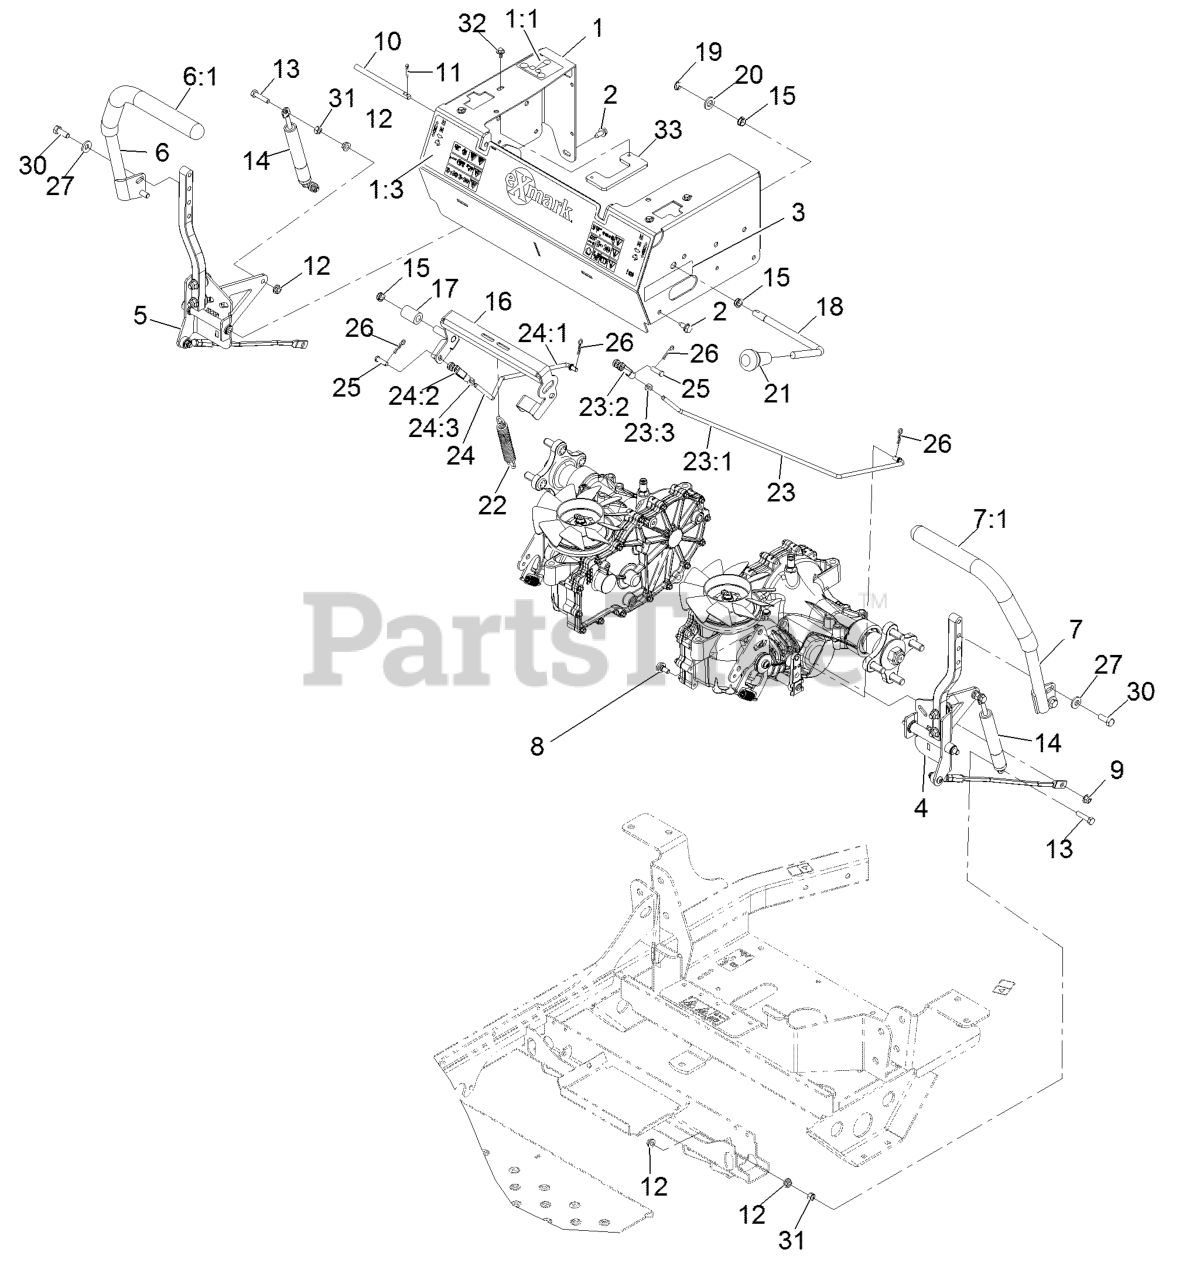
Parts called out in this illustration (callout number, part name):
1	ASM-MOT CTRL FRM W/DCL
1:1	DECAL-ROUTING, BELT
1:3	DECAL-CONSOLE
2	Screw-HWH 5/16-18 X 3/4 Tf
3	DECAL-S-SERIES
4	Motion Control ASM-LH
5	Motion Control ASM-RH
6	RH HANDLE ASM
7	LH HANDLE ASM
8	BOLT-SHOULDER,HFH
9	NUT-HF, NI
10	PIN-CONTROL PIVOT
11	PIN-COTTER
13	SCREW-HH
14	DAMPER-MOTION CONTROL
15	BUSHING,SNAP
16	ASM-BRAKE CENTER ARM
18	HANDLE,BRAKE
19	RING-RETAINING, EXTERNAL
20	WASHER-FLAT
22	SPRING-DECK, ENGAGEMENT
23	BRAKE LINKAGE ASM-LH
23:1	LINKAGE,BRAKE LH
23:2	YOKE-ADJUSTABLE
23:3	NUT-JAM
24	BRAKE LINKAGE ASM-RH
24:1	LINKAGE-BRAKE, RH
24:2	YOKE-ADJUSTABLE
24:3	NUT-JAM
25	PIN-CLEVIS
26	PIN-COTTER
27	WASHER-BELLEVILLE
30	SCREW-HH
31	NUT-HEX
32	SCREW-HHFTF
33	STOP-MOTION CONTROL
